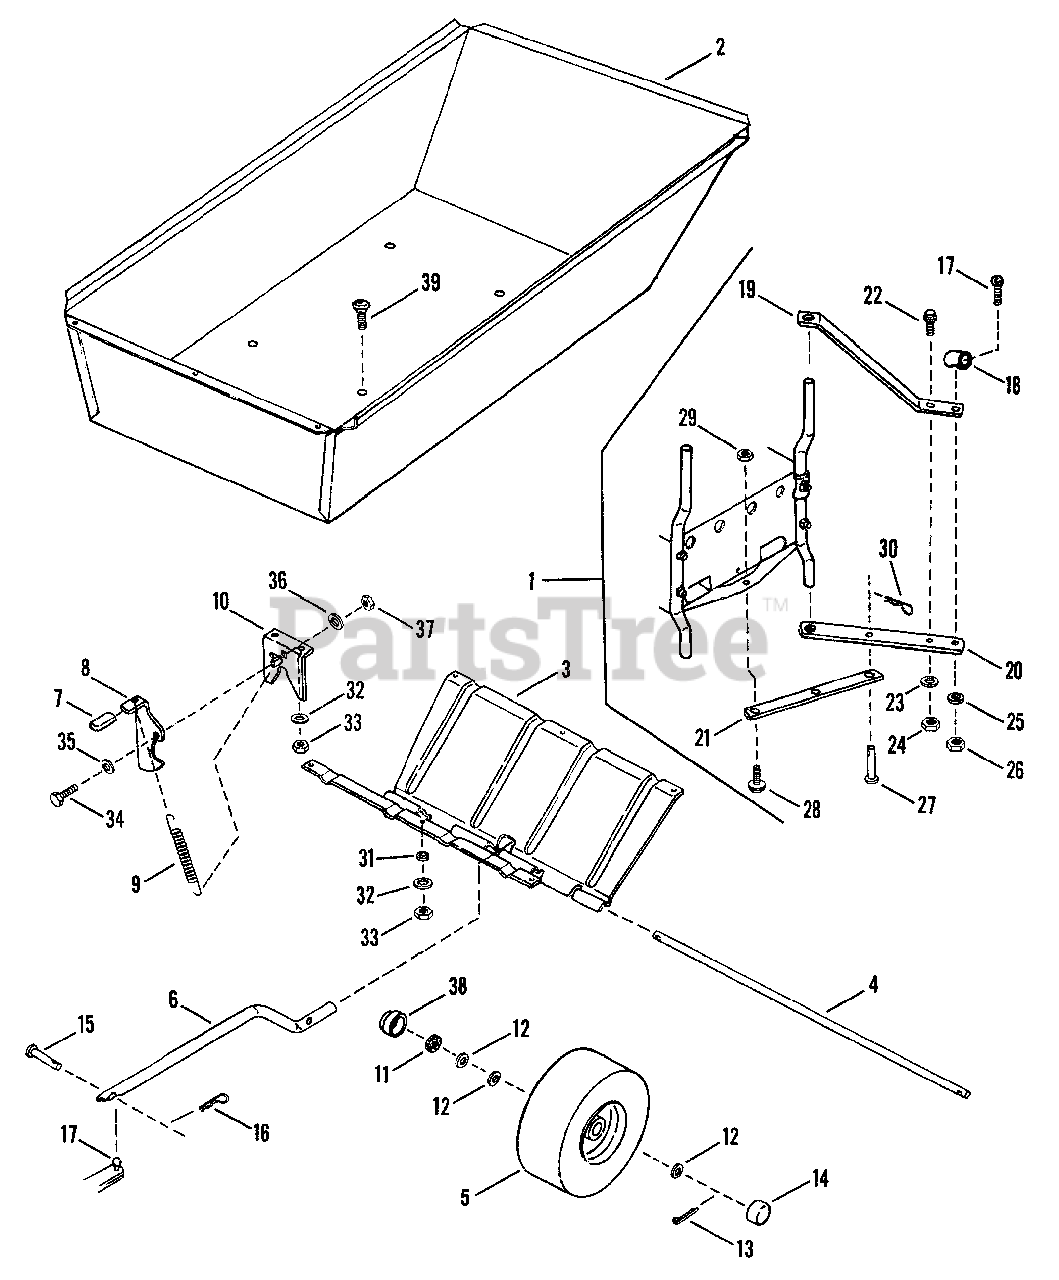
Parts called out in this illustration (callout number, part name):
1	ASSEMBLY, Hitch
2	BODY, Wagon Cart
3	SUPPORT, Axle
4	AXLE
5	ASSEMBLY, Tire & Rim
6	TONGUE
7	GRIP, Latch
9	SPRING, Latch
10	YOKE
11	WASHER, Felt
12	WASHER
13	COTTER-PIN, 5/32x1"
14	COVER, Dust
15	PIN, 3/8 Clevis
16	PIN, Hair
17	BALL, Hitch
18	COLLAR, Hitch
19	BAR, Upper Draw
20	BRACE, Draw Bar
21	BAR, Lower Draw
22	SCREW, 3/8-24x1" Hex Head Cap
23	WASHER, 3/8 Split Lock
24	NUT, 3/8-24 Hex
25	WASHER, 7/16 Split Lock
26	NUT, 7/16-20 Hex
27	PIN, Hitch Clevis
28	SCREW, 1/2-20x1" Hex Head Cap
29	NUT, 1/2-20 Hex Lock
30	PIN, Hair
31	RETAINER, 1/4 Bolt
32	WASHER, 1/4 Internal Tooth Lock
33	NUT, 1/4-20 Hex
34	BOLT, 5/16-18 Shoulder
35	WASHER, Spring
36	WASHER, 5/16 Split Lock
37	NUT, 5/16-18 Hex
38	DUST-CAP
39	BOLT, 1/4-20x3/4" Carriage
